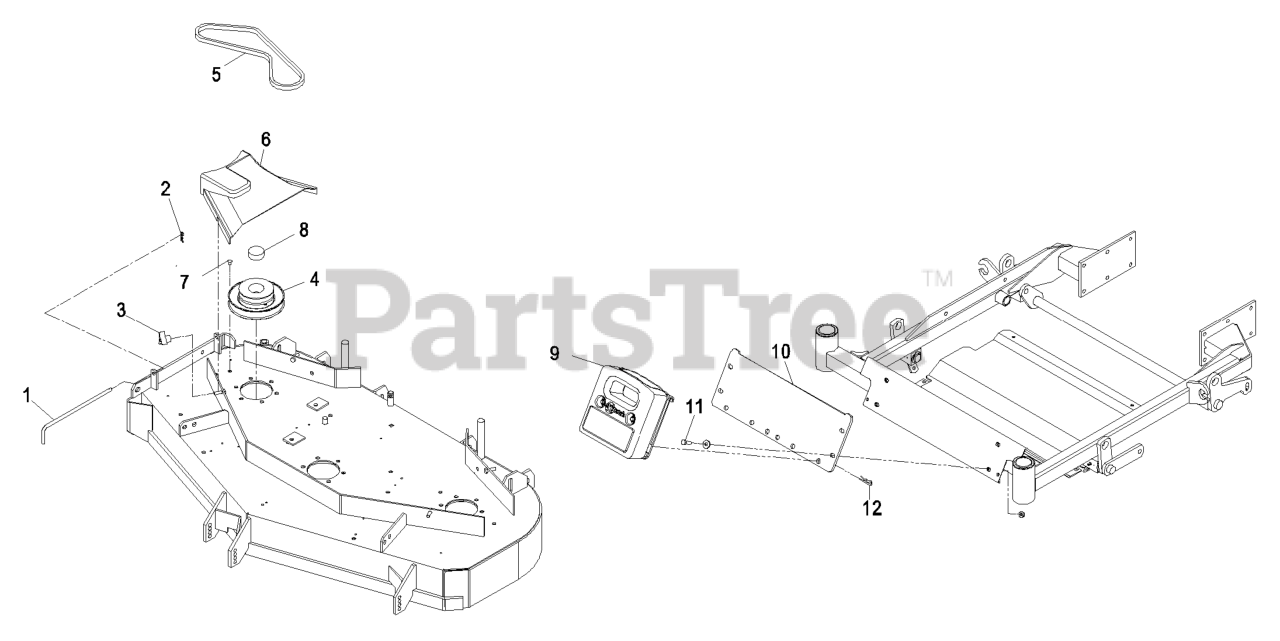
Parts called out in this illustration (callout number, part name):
1	PIN, CHUTE PIVOT PLTD
2	PIN-COTTER
3	KNOB-3 PRONG
4	SHEAVE, BLOWER DRIVE
5	BELT-BLOWER
6	COVER, BELT 44/48
7	SCREW-HH
8	PLUG, BLACK NYLON 1.75
9	ASM,CAST WEIGHT
10	PLATE,WEIGHT ASM MOUNT
11	SCREW-HH
12	PIN-HAIR
